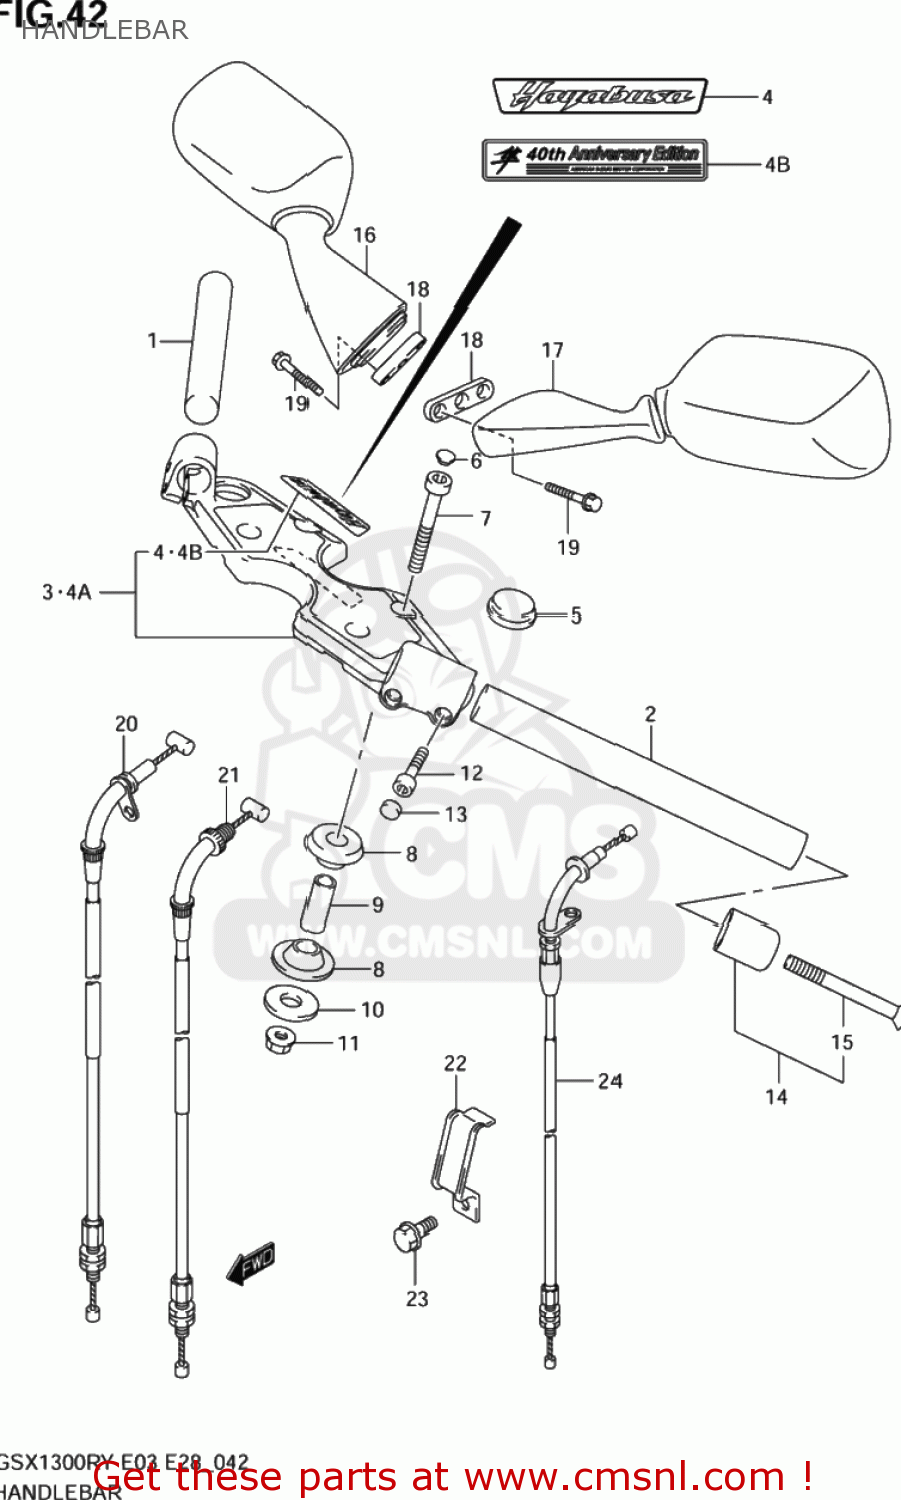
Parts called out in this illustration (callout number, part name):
1	HANDLEBAR,R
2	HANDLEBAR,L
3	HOLDER,HANDLEBAR
4	EMBLEM,HANDLE HOLDER
4A	HOLDER,HANDLEBAR
4B	EMBLEM,HANDLE HOLDER
5	CUSHION,HANDLE HOLDER
6	CAP,HANDLE HOLDER BRACKET BOLT
7	BOLT
8	CUSHION,UPR BRACKET
9	SPACER,STEERING STEM HEAD
10	WASHER(10.5X30X3.2)
11	NUT
12	BOLT(6X25)
13	CAP(OD:10)
14	BALANCER SET,HANDLEBAR
15	SCREW
16	MIRROR ASSY,RR VIEW,R
17	MIRROR ASSEMBLY,REAR VIEW
18	CUSHION,RR VIEW MIRRORR
19	BOLT,G/S SWITC
20	CABLE ASSY,THROTTLE NO.1
21	CABLE ASSY,THROTTLE NO.2
22	GUIDE,CABLE
23	BOLT(5X10)
24	CABLE,STARTER
